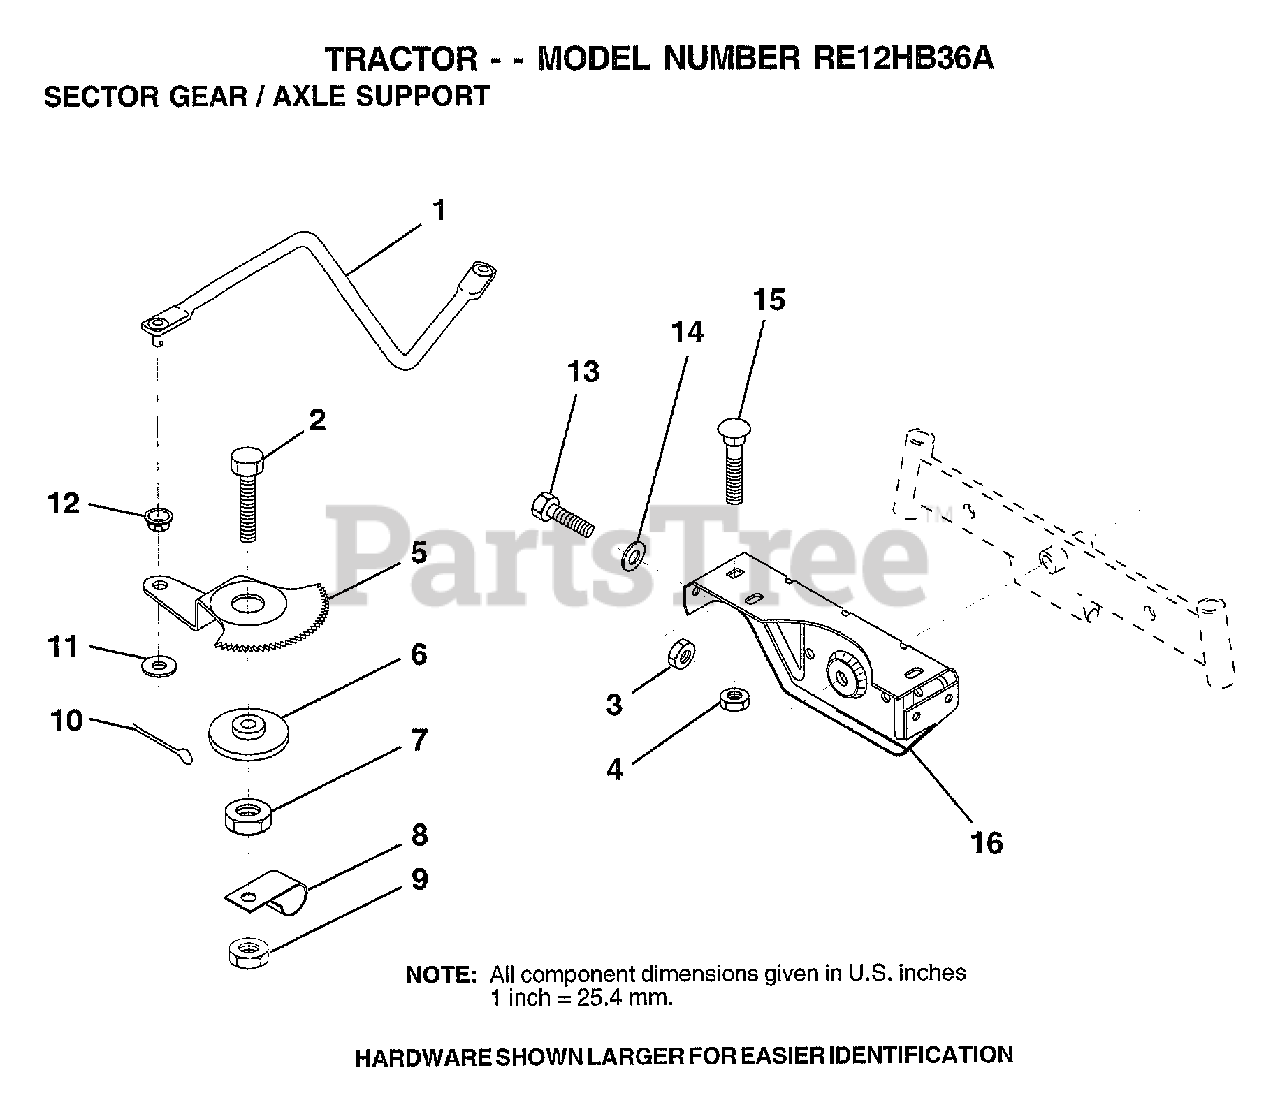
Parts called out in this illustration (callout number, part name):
1	DRAG LINK
2	"BOLT,HEX"
5	GEAR SECTOR
6	BUSHING
7	NUT
8	CLIP INSULATOR
9	NUT LTV
10	COTTER PIN
11	WASHER
12	BUSHING.DRAGLINK
13	BOLT
14	WASHER
15	BOLT
16	SUPT AXLE FRONT
